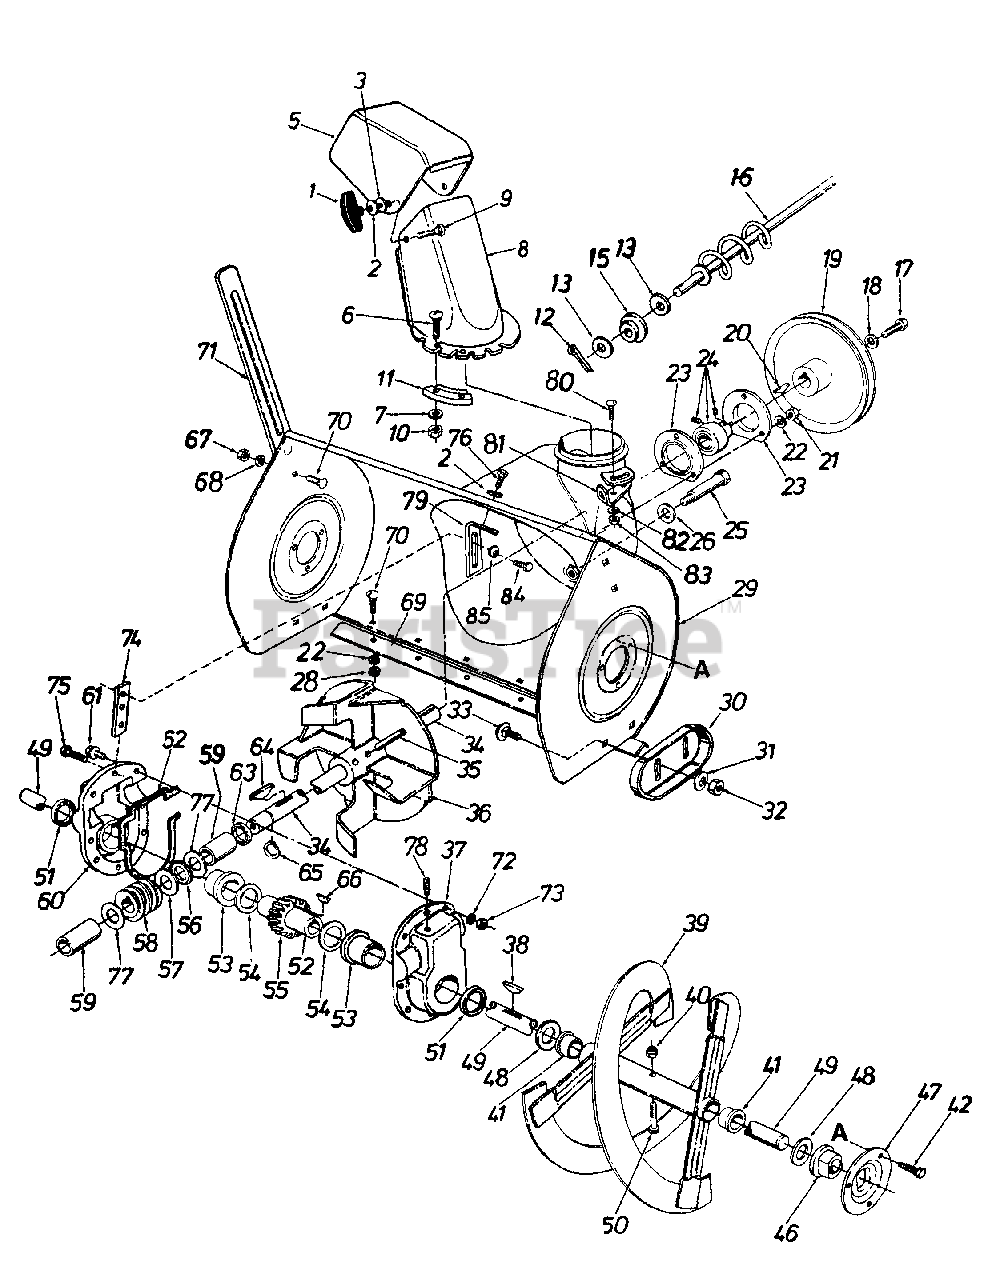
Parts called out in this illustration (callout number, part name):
1	Hand Knob Ass'y.
2	Bell-Wash .345 I.D. x .88 O.D. x .060
3	Fl-Wash .312 I.D. x 1.125 O.D. x .125
5	Top Chute
6	Truss Mach. Scr. 1/4-20 x .75"
7	Fl-Wash. 1/4" I.D.
8	Chute
9	Carr. Bolt 5/16-18 x 1.00" Lg.
10	Hex Cent. L-Nut 1/4-20 Thd.
11	Chute Flange Keeper
12	Cotter Pin
13	Fl-Wash .385" I.D. x .62"
15	Bushing
16	Chute Crank Ass'y.
17	Hex L-Scr. 5/16-18 x .88" Lg.
18	Bell-Wash .345 I.D . x .88
19	V-Pulley .875 I.D. x 10.12
20	#9 Hi-Pro Key 3/16 x 3/4" Dia.
21	Hex Nut 5/16-t 8 Thd.
22	L-Wash. 5/16" I.D.
23	Bearing Hsg.- Self Aligning Brg.
24	Self Aligning Brg .875 I.D.
25	Stud 3/8-16 x 2.75" Lg.
26	Bell-Wash .400 i.D. x .88 O.D. x .060
28	Hex Nut 5/16-18 Thd.
29	Blower Hsg. Ass'y.
30	Slide Shoe
31	Bell-Wash .400 I.D. x .88 O.D. x .060
32	Hex Jam Nut 3/8-16 Thd.
33	Carr. Bolt 3/8-16 x .62" Lg.
34	Blower Axle
35	Spring Pin Spiral 5/16" Dia. x 1.75" Lg.
38	#91 Woodruff Key 1/4" x 3/4" Dia.
39	Spiral Ass'y.- L.H.
40	Hex Ins. i-Nut 5/16-18 Thd.
41	Plastic Bushing
42	Hex Wash. Hd. Self-Tap Scr. 5/16-24 x .62" Lg.
46	Flange Brg w/Flats 1.0" I.D.
47	Bearing Hsg.- Spiral Hsg.
48	Fl-Wash. 1.06 I.D. x 1.75" O.D. x 100
49	Spiral Axle
50	Hex Bolt 5/16-18 x 1.75" Lg.
51	Oil Seal 1.50" I.D.
52	Worm Gear Shaft
53	Flange Brg 1.503 I.D
54	Fl-Wash. 1 5 I. D x 2.0 O.D.
55	Double Threaded Worm Gear
56	Thrust Brg .88 I.D. x 1.44 O.D. x 078
57	Fl-Wash. 88 I.D. x 1.40 O.D
58	Double Threaded Worm - L H.
59	Sleeve Brg. 875 I.D.
60	Complete Gear Hsg Half - R.H.
61	Hex Bolt 5/16-18 x 1 0" Lg.
63	Oil Seal .875" I.D.
64	#9 Hi-Pro Key 3/16 x 3/4" Dia.
65	Snap Ring -.875" Dia.
66	#91 Woodruff Key 1/4 x 3/4" Dia.
67	Hex Nut 5/16-18 Thd.
68	L-Wash. 5/16" I.0.
70	Carr. Bolt 5/16-18 x 62" Lg.
72	Wave Wash. 5/16" I.D.
73	Hex Ins. L-Nut 5/16-18 Thd
74	Gear Hsg. Support Plate
75	Hex Bolt 5/16-18 x 1.25"
76	Hex Wash. Hd. Self-Tap Scr. 5/16-18 x .75" Lg.
77	Fl-Wash .88 I.D. x 1.40 O.D.
78	Flller Plug
80	Carr. Bolt 5/16-18 x .75" Lg.
82	Bell-Wash .345 I.D. x 88"
83	Hex Nut 5/16-18 Thd.
84	Hex Bolt 1/4-28 x .75" Lg.
85	Bell-Wash .28" I.D. x 75" O.D.
